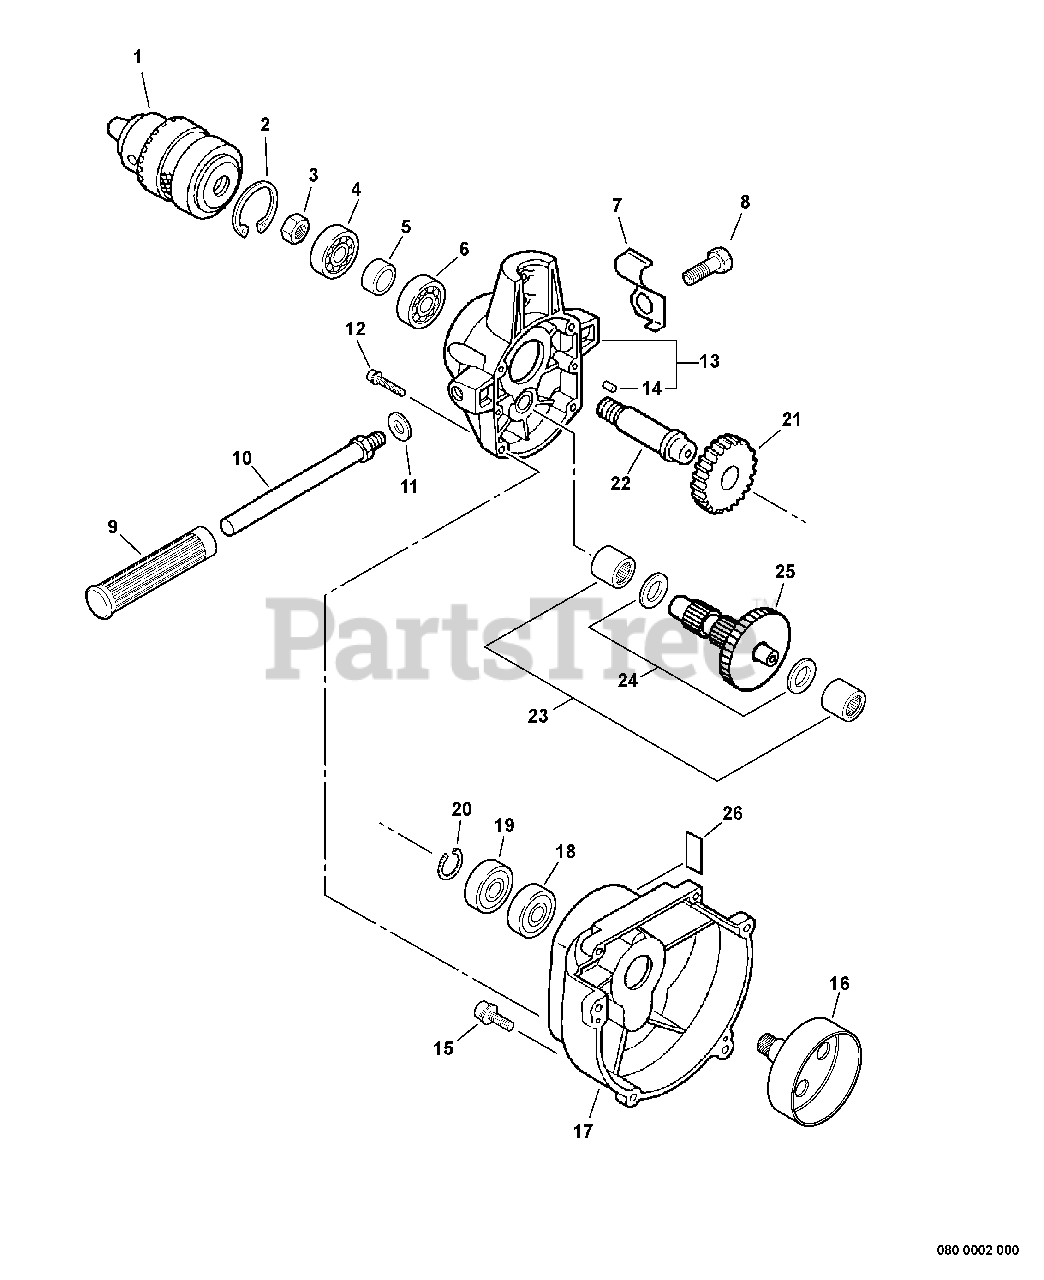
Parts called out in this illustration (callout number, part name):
2	RING, RETAINING - 32
3	NUT - 12
4	BEARING, BALL - 6002
6	BEARING, BALL - 6002
7	SPRING, FLAT
8	BOLT - 10X15
9	GRIP, HANDLE
10	HANDLE - FRONT
11	WASHER - 10
12	SCREW - 5X25
13	GEAR CASE ASSY
14	PIN - LOCATING
15	SCREW - 4X16
16	DRUM, CLUTCH
17	CASE, FAN
18	BEARING, BALL - 6001
19	BEARING, BALL - 6001
20	RING, RETAINING - 12
21	GEAR - SPUR
22	GEAR - SHAFT
23	BEARING, NEEDLE
25	GEAR - SHAFT
26	LABEL - HOT SURFACE
